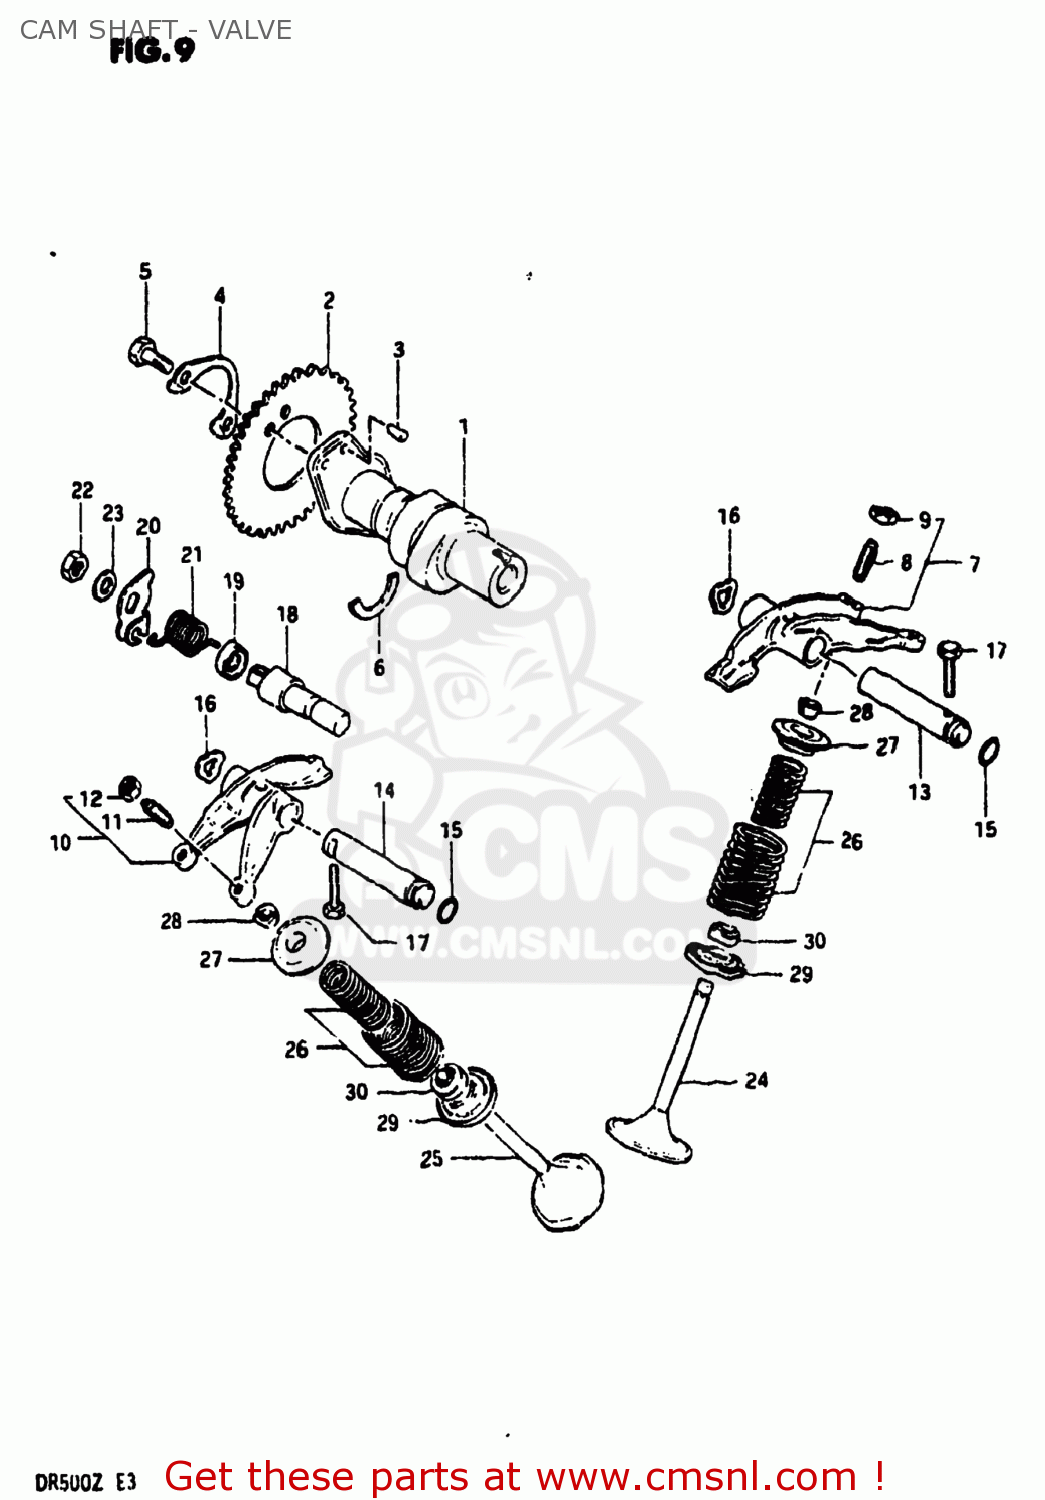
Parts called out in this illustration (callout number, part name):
1	CAMSHAFT
2	SPROCKET,CAMSHAFT(NT:42)
3	PIN
4	WASHER,CAM CHAIN SPROCKET
5	BOLT(6X12.5)
6	C RING
7	ARM,VALVE ROCKER
8	SCREW,TAPPET ADJUSTING
9	NUT,ADJUSTING SCREW
10	ARM,VALVE ROCKER,EXHAUST
11	SCREW,TAPPET ADJUSTING
12	NUT,ADJUSTING SCREW
13	SHAFT,VALVE ROCKER ARM
14	SHAFT,VALVE ROCKER ARM
15	O-RING
16	WASHER
17	BOLT(6X23)
18	SHAFT,DECOMPRESSION
19	OIL SEAL
20	LEVER,DECOMPRESSION SHAFT
21	SPRING
22	NUT 8MM
23	WASHER
24	VALVE,INTAKE
25	VALVE,EXHAUST
26	SHIM,TAPPET
27	RETAINER,VALVE SPRING
28	COTTER VALVE
29	SEAT,VALVE SPRING
30	SEAL,OIL(7X14.4X9)
